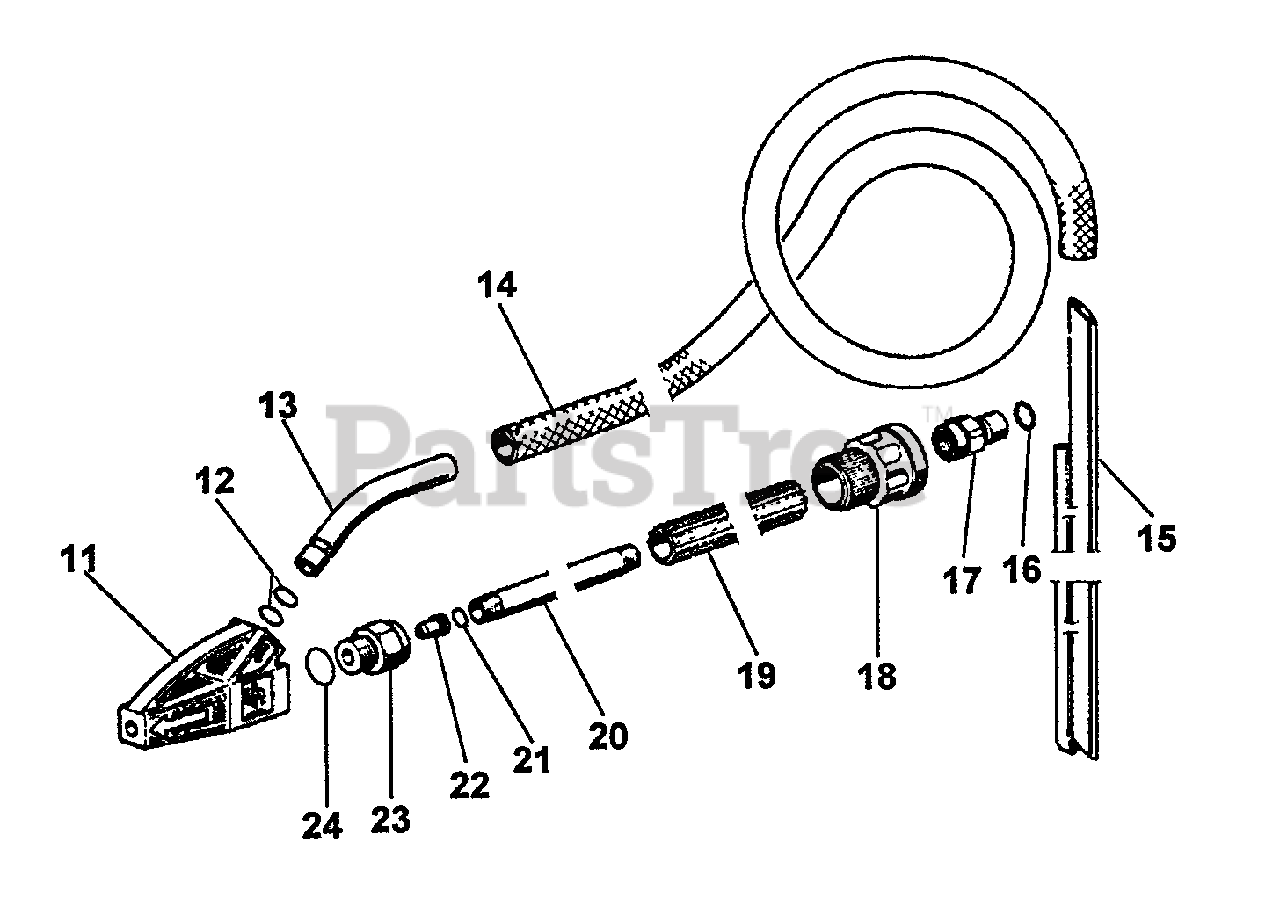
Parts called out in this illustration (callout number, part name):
11	NOZZLE, SAND
12	O-RING
13	CONNECTOR, SAND TUBE
14	TUBE, SAND
16	O-RING
17	COUPLING, MALE
18	NUT, RING
19	GRIP, HANDLE
20	PIPE
22	NOZZLE, SAND BLASTING
23	HOLDER, NOZZLE
24	O-RING, 0.614×0.070
